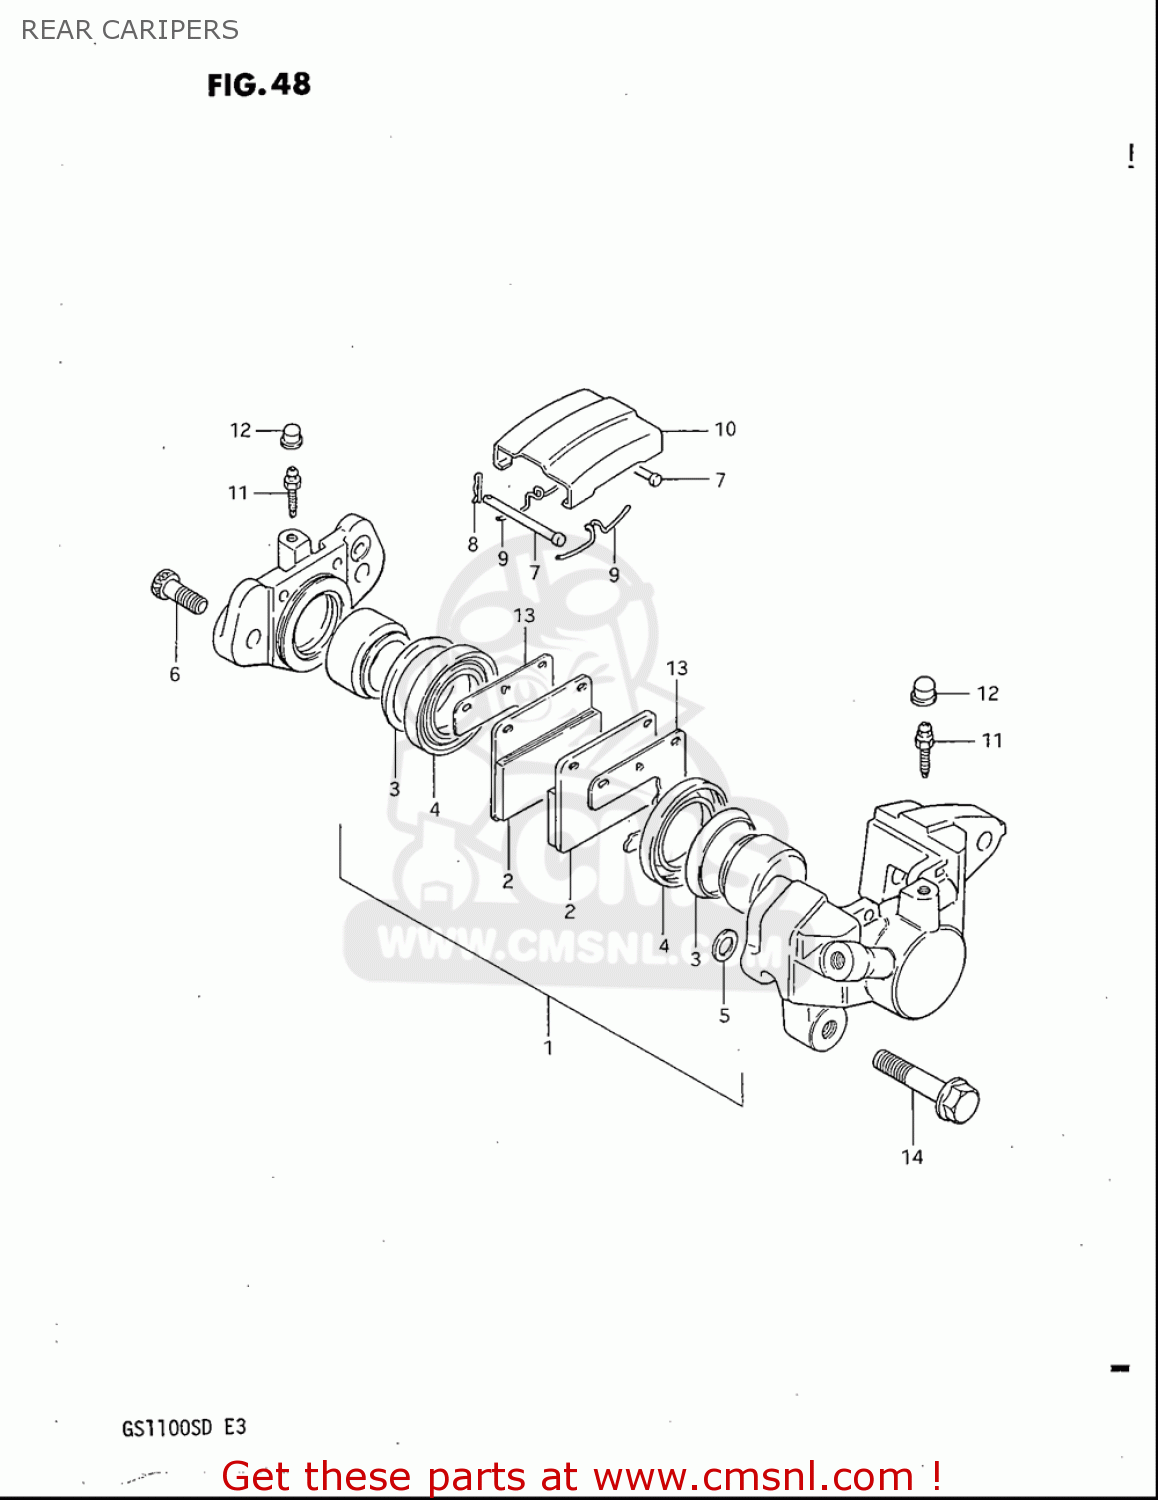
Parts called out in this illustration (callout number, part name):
1	PISTON SET
2	PAD SET (NAS)
3	SEAL,PISTON
4	BOOT,PISTON
5	SEAL,PISTON
6	BOLT,HOUSING
7	PIN,PAD
8	CLIP,PAD PIN
9	SPRING
10	COVER,DUST
11	BLEEDER
12	CAP,BLEEDER PLUG
13	SHIM,RR CALIPER
14	BOLT
